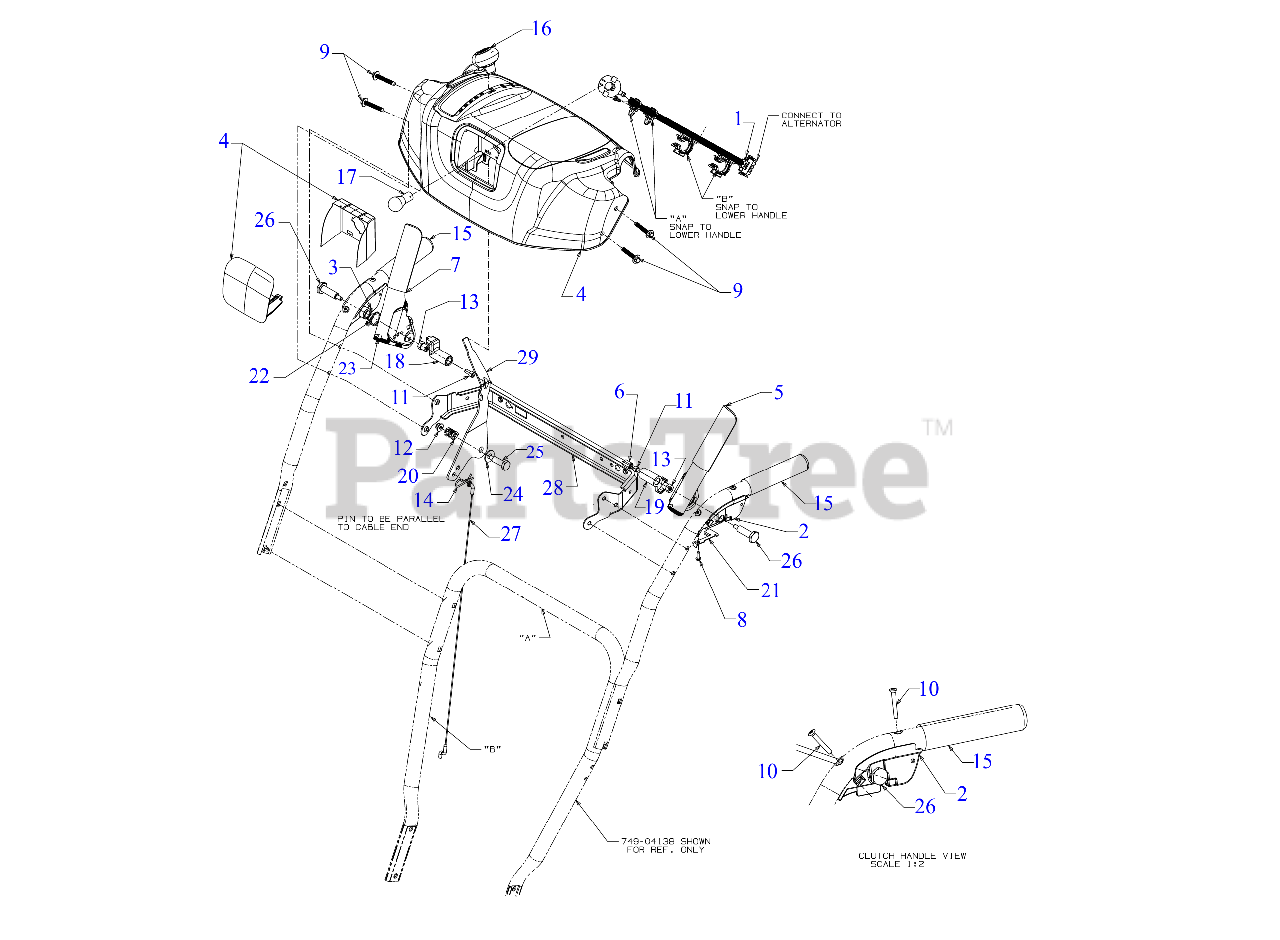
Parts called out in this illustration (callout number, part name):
1	LIGHT HARNESS
2	CLUTCH LOCK HANDLE ASSEMBLY (LH)
3	CLUTCH LOCK HANDLE ASSEMBLY (RH)
4	HANDLE PANEL ASSEMBLY (BLACK)
5	HANDLE ASSEMBLY (LH)
6	PIVOT ROD
7	HANDLE ASSEMBLY (RH)
8	SCREW #8-16 x .50
9	SCREW 1/4-20 x 1.625
10	SCREW #10-24 x 1.375
11	SCREW 1/4-20 x .50
12	FLANGE LOCK NUT
13	HEX NUT W/PATCH
14	INTERNAL COTTER PIN
16	SHIFT KNOB
17	LAMP-12 VOLT
18	LOCK PLATE
19	CLUTCH LOCK CAM
20	COMPRESSION SPRING
21	CLUTCH SPRING
22	TORSION SPRING
23	RUBBER BUMPER
24	FLAT WASHER .40X.88X.060
25	SHOULDER SCREW
26	SHOULDER SCREW .437 x 1.345 1/4-20
27	SPEED SELECTOR CABLE (PLASTIC)
28	HANDLE SUPPORT BRACKET (POWDER BLACK)
29	SHIFT LEVER
